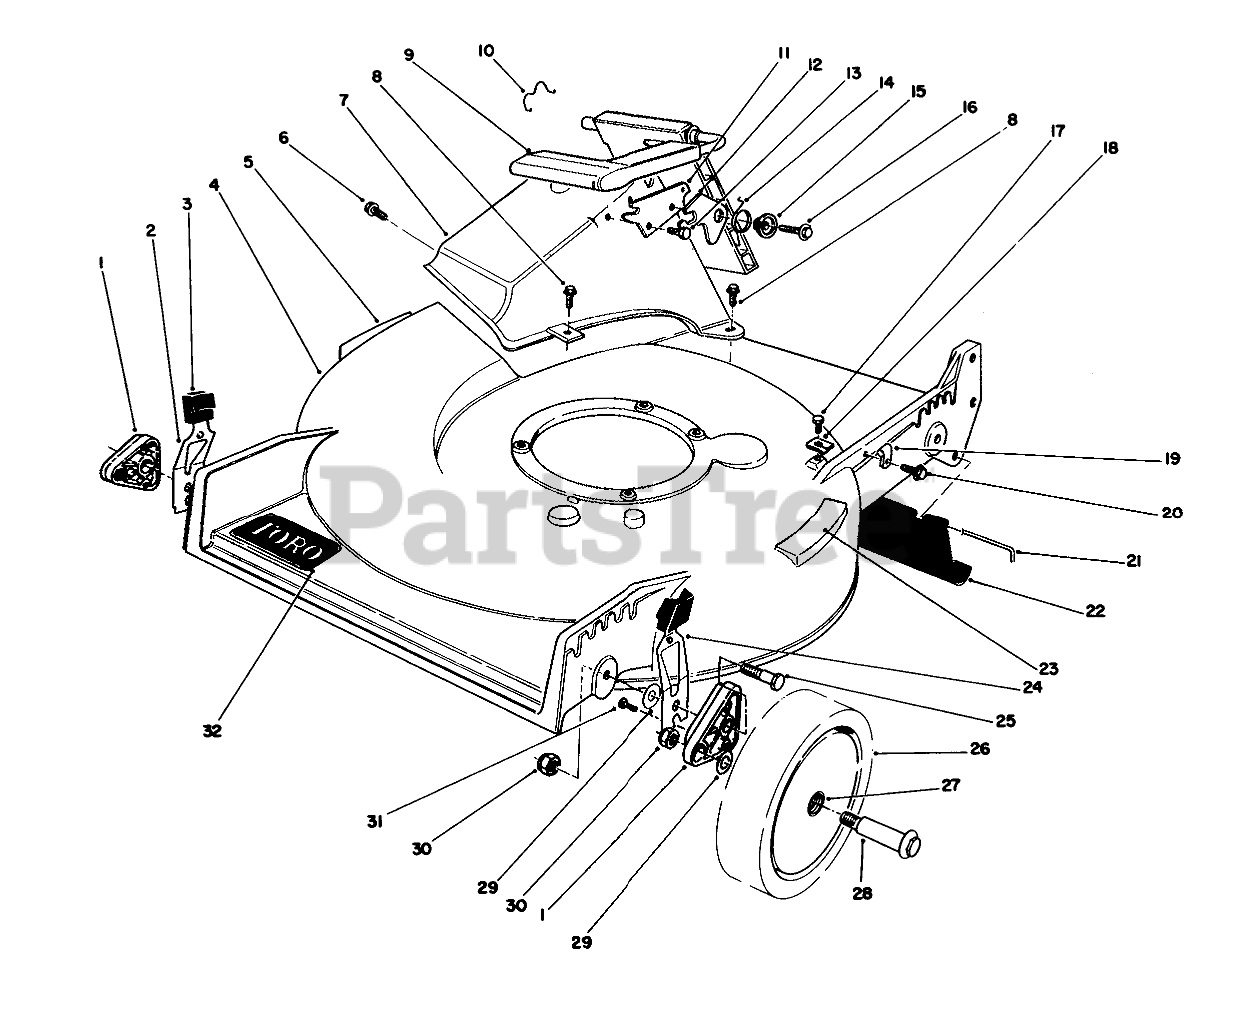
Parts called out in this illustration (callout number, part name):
1	ARM-PIVOT, FRONT
2	RH SPRING ARM ASSEMBLY
3	KNOB-ARM
4	Housing (Incl. Ref. #5 & 23)
5	Decal-Danger
6	SCREW AND WASHER ASM
7	Tunnel Discharge
8	SCREW-HWH
9	Discharge Door Assembly
10	DOOR RET SPRING
11	DOOR LATCH PLATE
12	SAFETY LATCH
13	SCREW-PLASTITE
14	TORSION SPRING
15	DOOR SPACER
16	SCREW-HWH
17	SCREW-HWHTF
18	CLAMP-CABLE
19	CLAMP-CABLE
20	SCREW
21	ROD-SHIELD
22	SHIELD-TRAILING
23	STEP PAD DECAL
24	LH SPRING ARM ASSEMBLY
25	BOLT-SHOULDER
26	Wheel & Tire Assembly (Incl. Ref. #27)
27	BUSHING
28	WHEEL BOLT
29	WASHER
30	Nut
31	SCREW-HWH
32	DECAL
